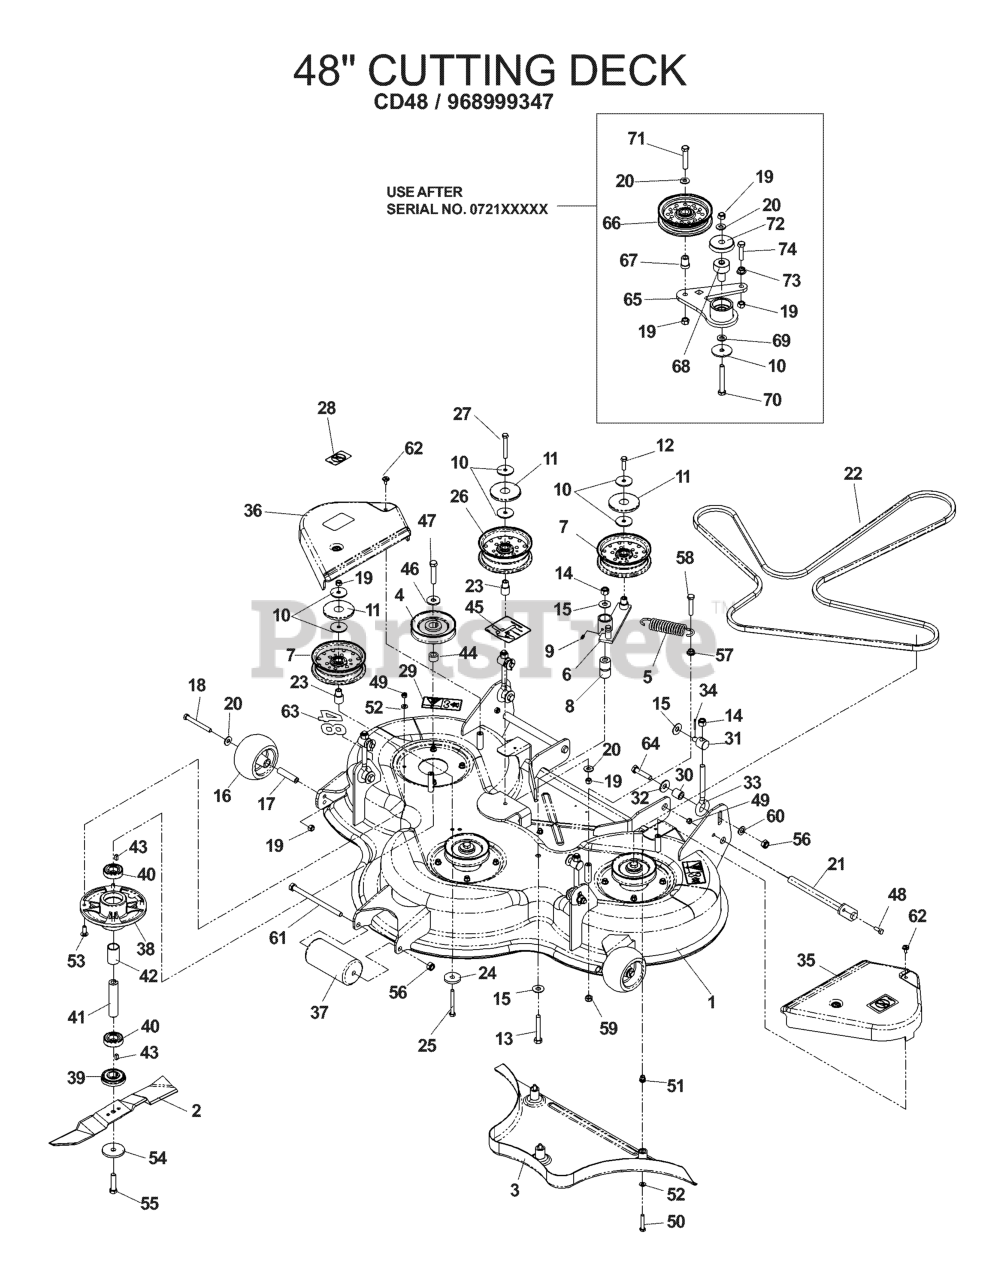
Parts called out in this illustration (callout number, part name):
4	PULLEY, 48
7	IDLER PULLEY
8	PIVOT BUSHING
9	ZERK
10	WASHER, 3/8 SPEC
11	TOP DUST CAP
12	HCS 3/8C X 1 1/4 GR5
13	SCREW, 1/2C X 3 HEX CAP
14	NUT 1/2-13 HEX NYLOC ZD
15	WASHER 1/2 FLAT
16	ANTI-SCALP ROLLER
18	HCS 3/8C X 3 1/2
19	NUT 3/8-16 NYLOC
20	WASHER 3/8 FLAT
22	DECK BELT, 48 CMB
23	IDLER BUSHING
24	SPINDLE WASHER
25	HCS 3/8C X 3
26	IDLER PULLEY (TALL)
27	SCREW 3/8C X 2 3/4 HEX CAP
28	DECAL, NO STEP
29	DECAL, BELT DRIVE
32	SPRING WASHER - .50
34	PIN COTTER 1/8 X 1 ZD
35	BELT SHIELD LT
36	BELT SHIELD RT
37	ROLLER
38	BEARING HOUSING
40	BALL BEARING
44	KEY RETAINER
45	DECAL, BELT ROUTING
48	SCREW 8X20
49	LOCKNUT M8
50	SCREW
52	WASHER BRB 8.4X17
59	NUT
60	WASHER - M12
65	ARM, IDLER - W/BEARINGS
66	IDLER PULLEY
67	BUSHING, IDLER FLANGE
68	PIVOT, BEARING
69	WASHER 3/8 SAE FLAT
70	HEX SCREW 3/8-20 X 2.75
71	HCS 3/8C X 2
72	SHIELD, DUST
73	NUT 3/8C WHIZ
74	HCS 3/8C X 1 1/2
